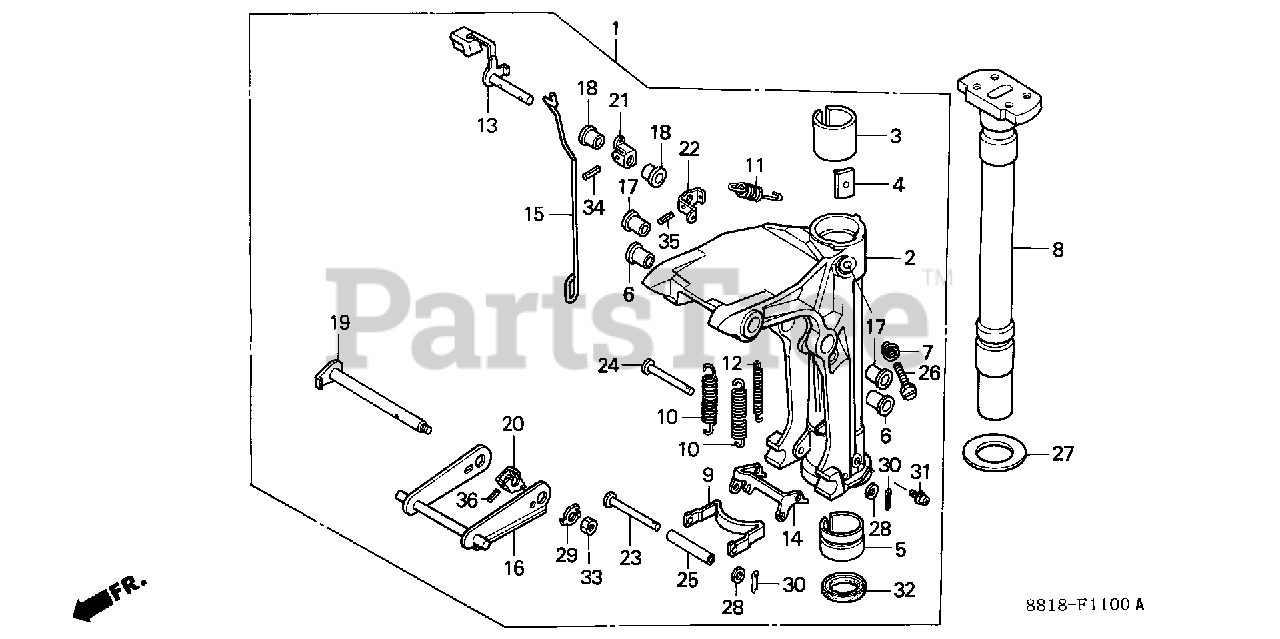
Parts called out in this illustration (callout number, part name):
1	CASE ASSY., SWIVEL *NH282MU* (OYSTER SILVER METALLIC-U)
2	CASE, SWIVEL *NH282MU* (OYSTER SILVER METALLIC-U)
3	LINER, SWIVEL CASE
4	BLOCK, FRICTION
5	BUSH, SWIVEL SHAFT
6	BUSH, SWIVEL CASE
7	SPRING, FRICTION ADJUSTING
8	SHAFT, SWIVEL *NH282MU* (OYSTER SILVER METALLIC-U)
9	HOOK, REVERSE LOCK
10	SPRING, REVERSE LOCK
11	SPRING, TILT LEVER
12	SPRING, TILT LINK
13	LEVER, TILT
14	ARM, REVERSE LOCK
15	ROD, RELEASE SWIVEL CASE
16	ARM, TILT
17	BUSH, TILT LEVER
18	BUSH, TILT LEVER
19	SHAFT, TILT
20	BRACKET, TILT SHAFT
21	BRACKET, RELEASE ROD (NOT AVAILABLE)
21	BRACKET, RELEASE ROD
22	BRACKET, TILT LEVER
23	SHAFT, REVERSE LOCK (A)
24	SHAFT, REVERSE LOCK (B)
25	COLLAR, REVERSE LOCK
26	BOLT, SPECIAL (8X20)
27	WASHER, THRUST
28	WASHER, PLAIN (6MM)
29	WASHER, LOCK
30	PIN, SPLIT (2.0)
31	NIPPLE, GREASE
32	OIL SEAL (32X37X7) (NOK)
33	NUT, HEX. (6MM)
34	PIN, SPRING (3.0X22)
34	PIN, SPRING (2.5X22)
35	PIN, SPRING (3.0X25)
35	PIN, SPRING (2.5X25)
36	PIN, SPRING (3.0X25)
36	PIN, SPRING (3X25)
